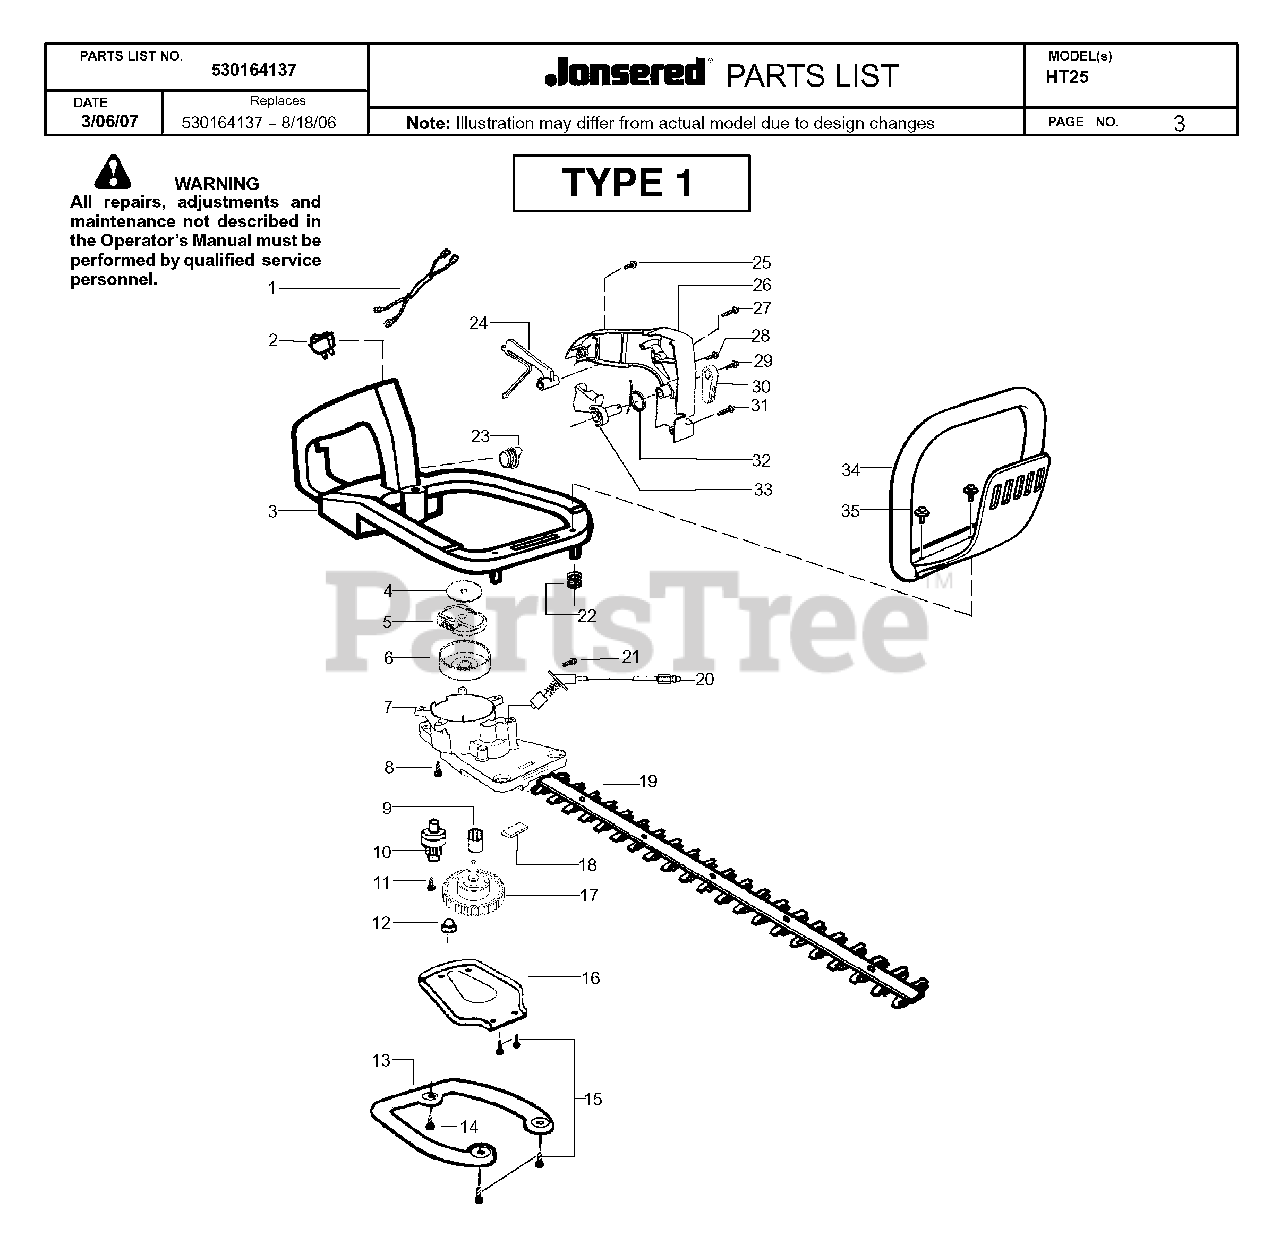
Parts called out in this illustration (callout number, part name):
8	SCREW-10-14 X 13/16 (PL
11	SCREW-10-16 X 1/2, TYPE 2
12	BLADE BUSHING
13	ISOLATOR PLATE
16	PLATE-GEARBOX COVER
19	BLADE ASSEMBLY
22	ANTIVIBE MOUNT
23	FUEL CAP ASSY W/RET.
29	SCREW 8-16 X 9/16 (PLAS
31	SCREW #10 PLASTITE 1.362
